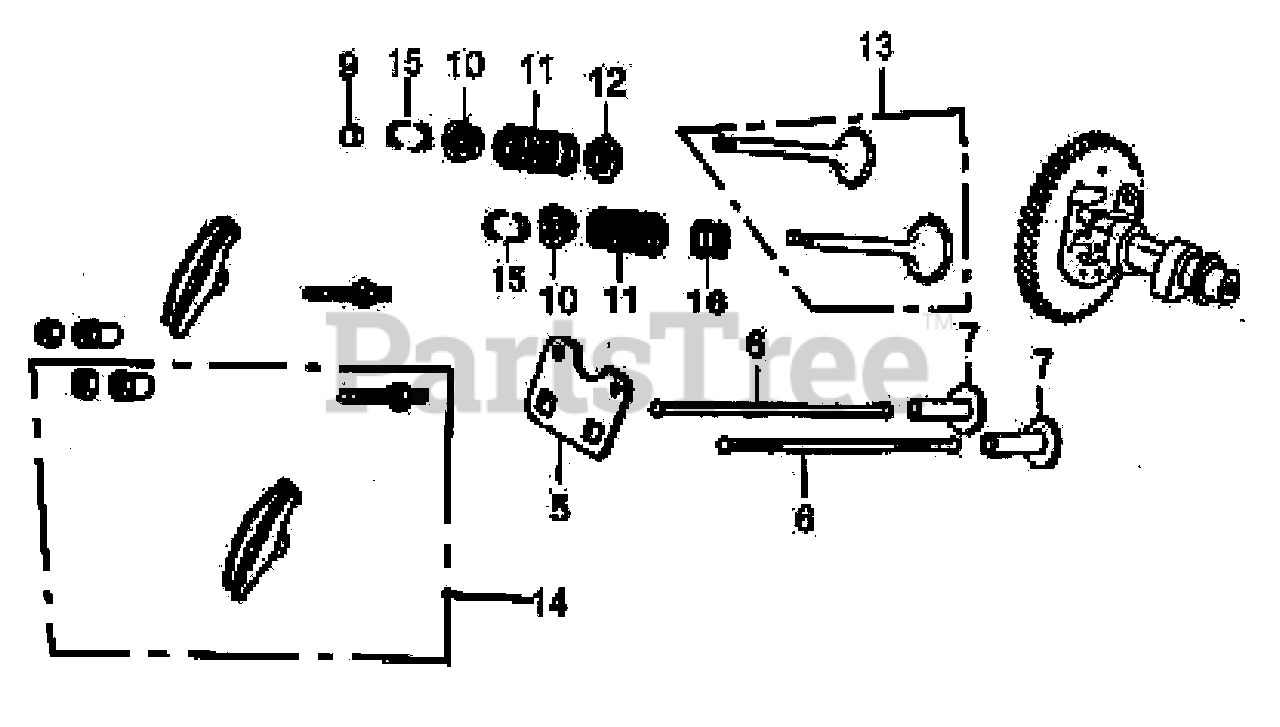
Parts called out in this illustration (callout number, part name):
5	PLATE, PUSH ROD GUIDE
6	ROD, PUSH
7	LIFTER, VALVE
9	ROTATOR, VALVE
10	RETAINER, VALVE SPRING
11	SPRING, VALVE
12	SEAT, VALVE SPRING
13	VALVE ASSY.
14	RPCLER AR, ASSY.
15	LOCKER, VALVE
16	SEAL, VALVE STEM
